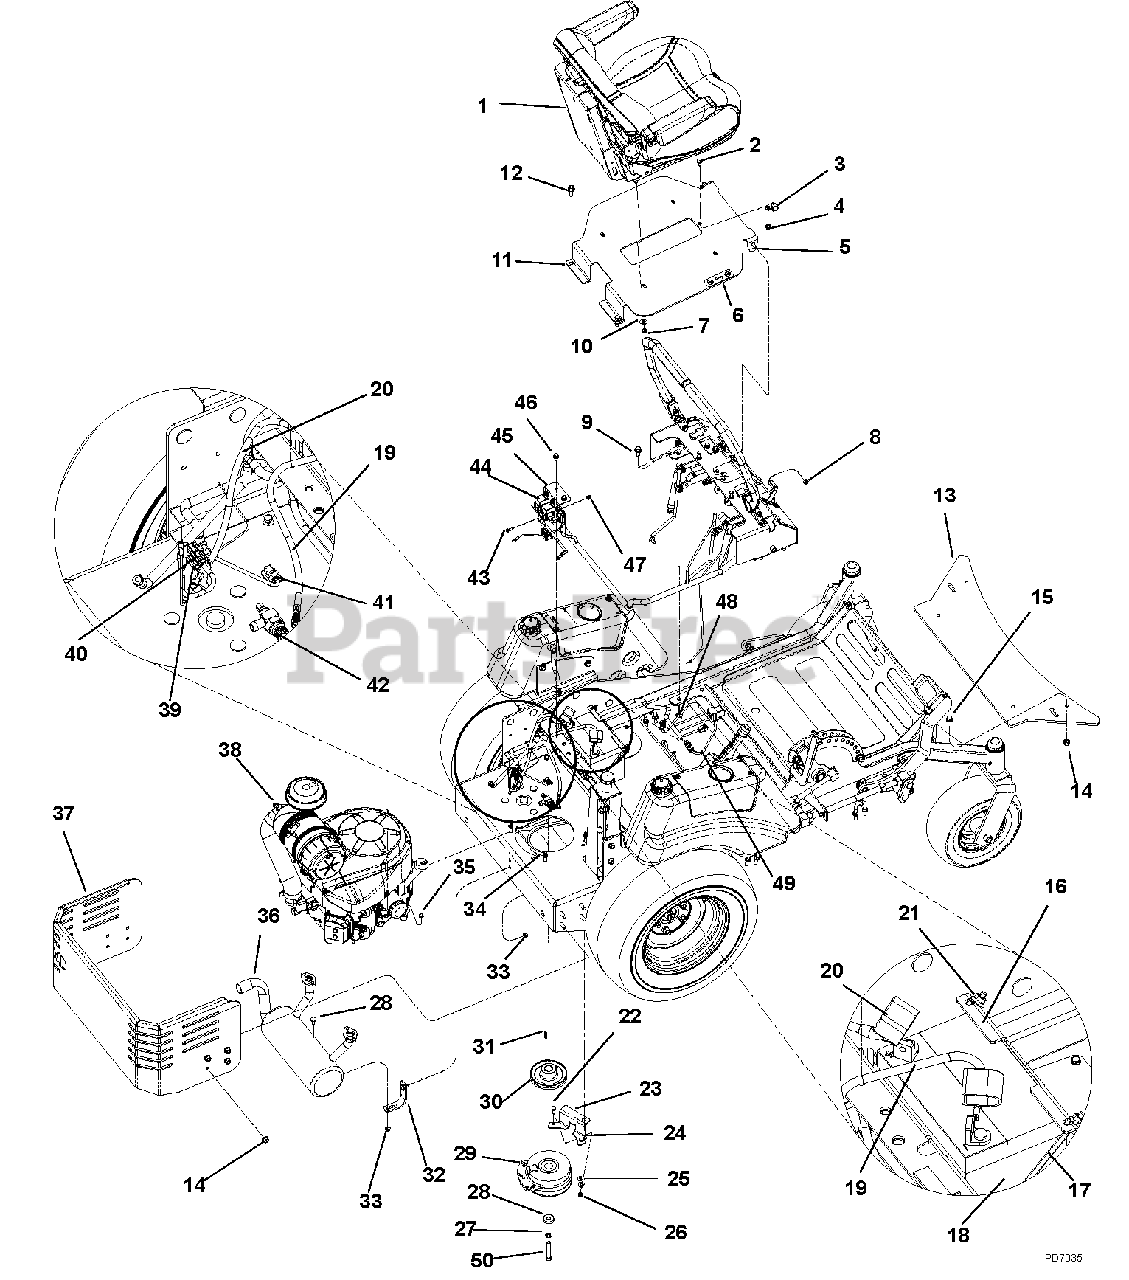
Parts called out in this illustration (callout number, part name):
1	SEAT, FULL SUSPENSION
2	BOLT, M8 X 1.25 X 20 CRG 8.8 Y
3	P-CLIP, .750 INSULATED
4	LOCKNUT, FL, ISO7043, M8 X 1.25
5	BOLT, 1/2 X 1.06 X 3/8-16 SLD 5 Y
6	LABEL - PARK BRAKE DIRECTION
7	LOCKNUT, 5/16-18 NYLOCK Y
8	NUT, 3/8 LOCK
9	SCREW, HEX M10 X 1.5 X 25
10	WASHER, .344 X 1.00 X .134 FLAT Y
11	PLATE, SEAT S/O
12	SCREW, HEX , FL, JDS123, M10 X 1.5 X 30
13	PLATE, WEIGHT
14	LOCKNUT, FL, ISO7044, M10-1.50
15	SCREW, HEX , FL, JDS121, M10 X 1.5 X 40
16	HOLDER, BATTERY
18	BATTERY, 12V-U1-CCA 400 MIN
19	CABLE, BATTERY -20" GROUND
20	CABLE, BATTERY POSITIVE
21	NUT-1/4" FLANGE PREVAILING TORQUE
22	BOLT, 5/16-18 X .750 HEX 5 Y
23	BRACKET, CLUTCH STOP
24	BOLT, 7/16-14 X 1.25 HEX 5 Y
25	WASHER, .250 REG FLAT Y
26	LOCKNUT, 5/16-18 CENTER Y
27	WASHER, .438 MED SPRG LOCK Y
28	SPACER, .468 X 1.38 X .375 Y
30	PULLEY, V-BELT 4.78PD X 1.000 W/ KEY
31	KEY, .250 X .250 X .995 TPR
32	BRACKET, MUFFLER
33	LOCKNUT, M8 X 1.25, FLANGED ZN
34	BOLT, 5/16-18 X 1.75 HEX 5 Y
35	LOCKNUT, 5/16-18 CROWN Y
36	MUFFLER, MINI-Z
37	BUMPER, REAR EKW
38	ENGINE, KAE25HP FH721V
39	HARNESS, PIGTAIL
40	FUSIBLE LINK, 10"
41	HARNESS, SEAT RELAY
42	OIL DRAIN FITTING
43	SCREW, HEX JDS123, M6 X 1 X 16 Z
44	RELAY, SEALED W/ BRACKET
45	BRACKET, ELECTRIC MOUNTING
46	SCREW, HEX , FL, JDS123, M8 X 1.25 X 16
47	HARNESS, WIRING
48	LOCKNUT, F1.ISO7043M6 X 1-10
49	LOCKNUT, M10 X 1.50 WHIZ GR10 Y
50	BOLT, 7/16-20 X 2.75 HEX 5 Y
